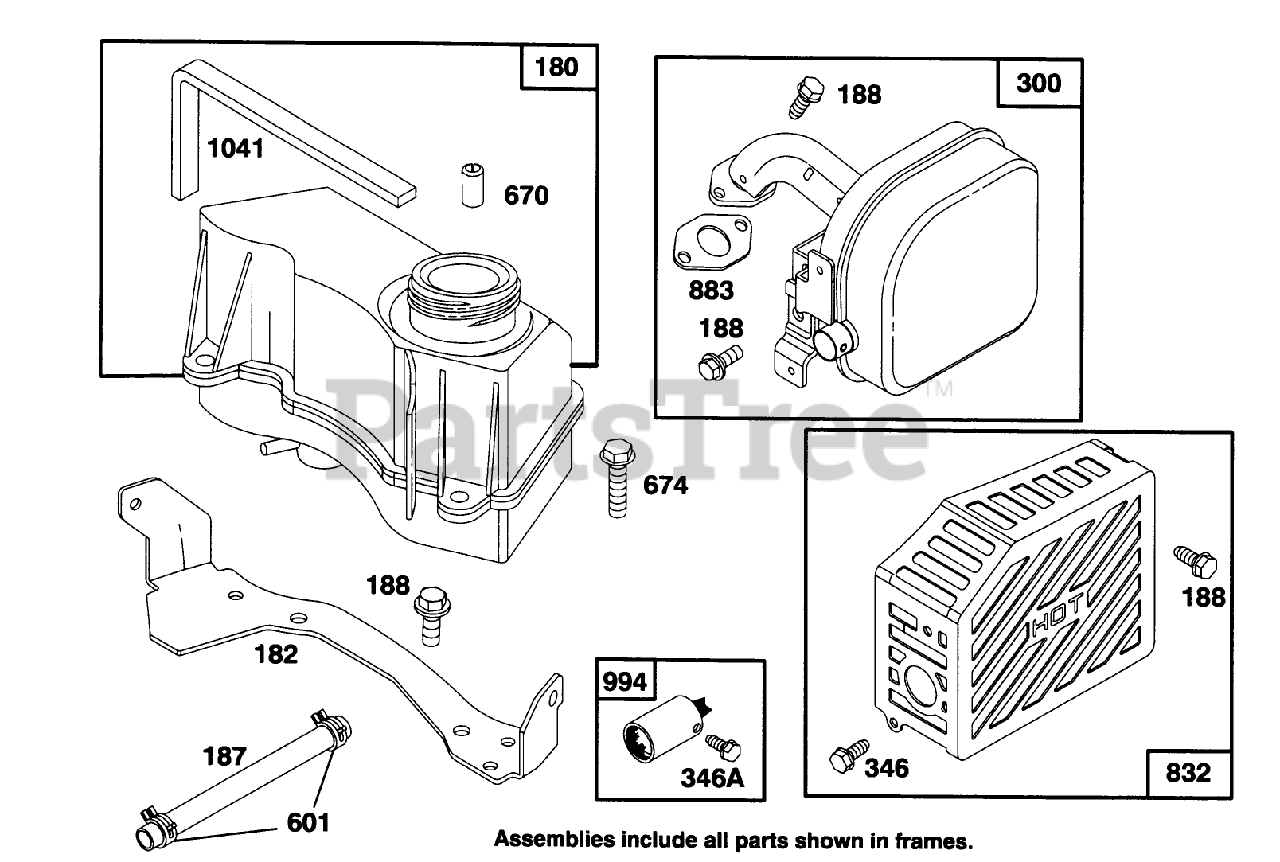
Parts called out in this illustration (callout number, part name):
180	TANK ASSY - FUEL
188	SCREW - SEM
300	MUFFLER - EXHAUST
346	SCREW - SELF-TAPPING
601	CLAMP - CL PIPE
670	SPACER
674	SCREW - HEX HEAD
